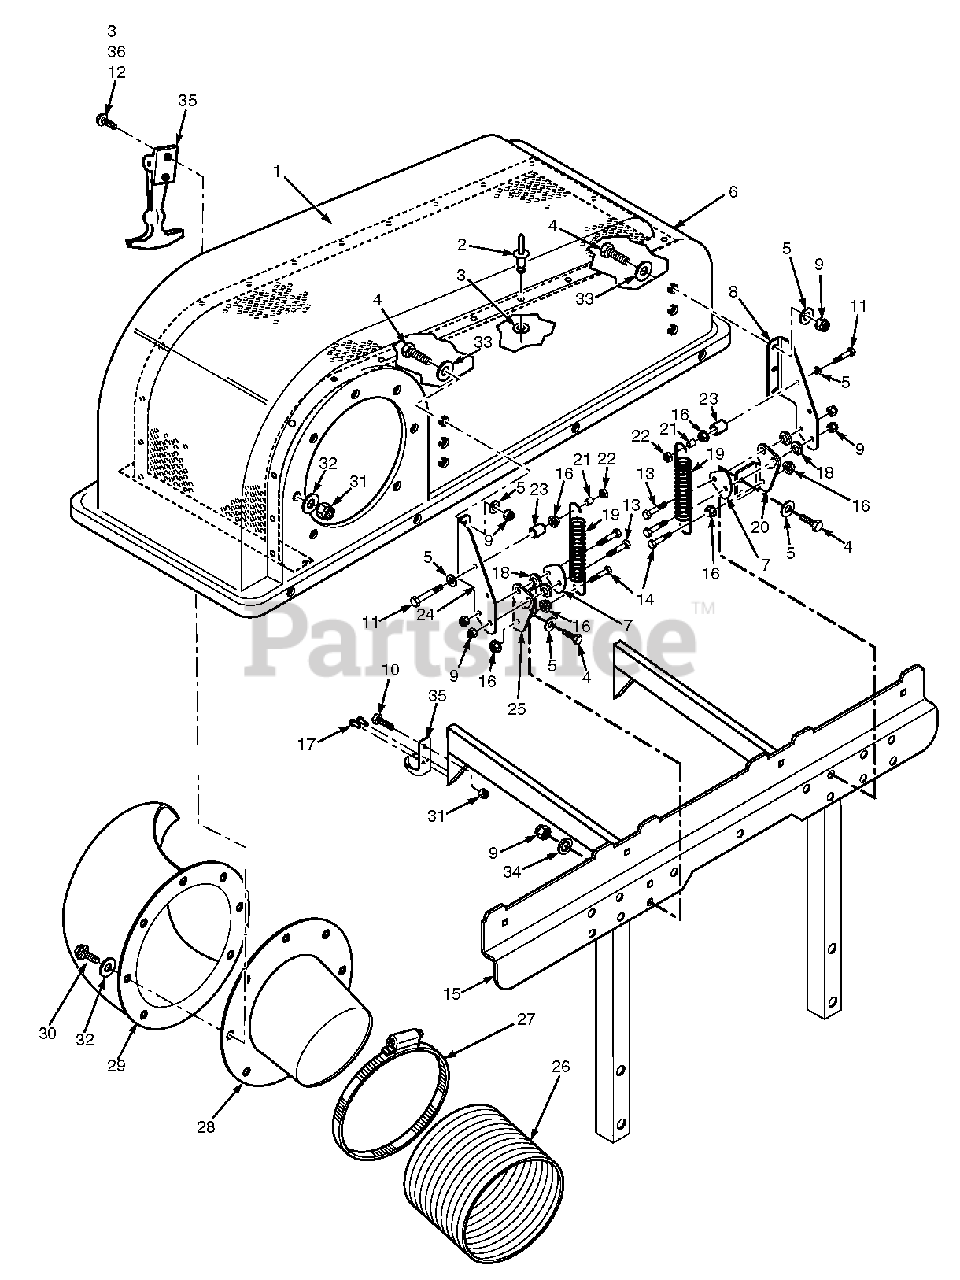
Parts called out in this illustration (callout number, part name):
1	Screen, Catcher Hood
2	Pop Rivet, 3/16 x .652
3	Flatwasher, 3/16-.196 x .469 x .048
4	Bolt, Hex Head 3/8-16 x 1-1/4"
5	Flatwasher, 3/8-.391 x .938 x .105
6	Hood Assembly, GC-STT
7	Guard, GC Hinge
8	Hinge, Upper LH
9	Nut, Elastic Stop 3/8-16
10	Bolt, Hex Head 5/16-18 x 3/4"
11	Bolt, Hex Head 3/8-16 x 2-1/4"
12	Nut, Elastic Stop 7/16-14
13	Bolt, Hex Head 3/8-16 x 1-1/2"
14	Bolt, Hex Head 3/8-16 x 1-3/4"
15	Support Weldment, Bag Frame
16	Nut, Serrated Flange 3/8-16
17	Pop Rivet, 3/16 x .402
18	Bushing, Hopper Pivot
19	Spring, Hood Hinge
20	Hinge, Lower LH
21	Spacer
22	Locknut, 3/8-16
23	Spacer
24	Hinge, Upper RH
25	Hinge, Lower RH
26	Hose, 8" Dia. x 53"
27	Clamp, 8-5/8" Max Dia.
28	Tube, Filler
29	Elbow
30	Bolt, Hex Head 5/16-18 x 1-1/4"
31	Nut, Elastic Stop 5/16-18
32	Flatwasher, 5/16-.375 x .875 x .083
33	Flatwasher, 3/8- .406 x 1-1/2" x .179
34	Lockwasher, 3/8" Spring
35	Latch
36	Screw, #10-32 x 3/4"
37	Nut, Elastic Stop #10-32
